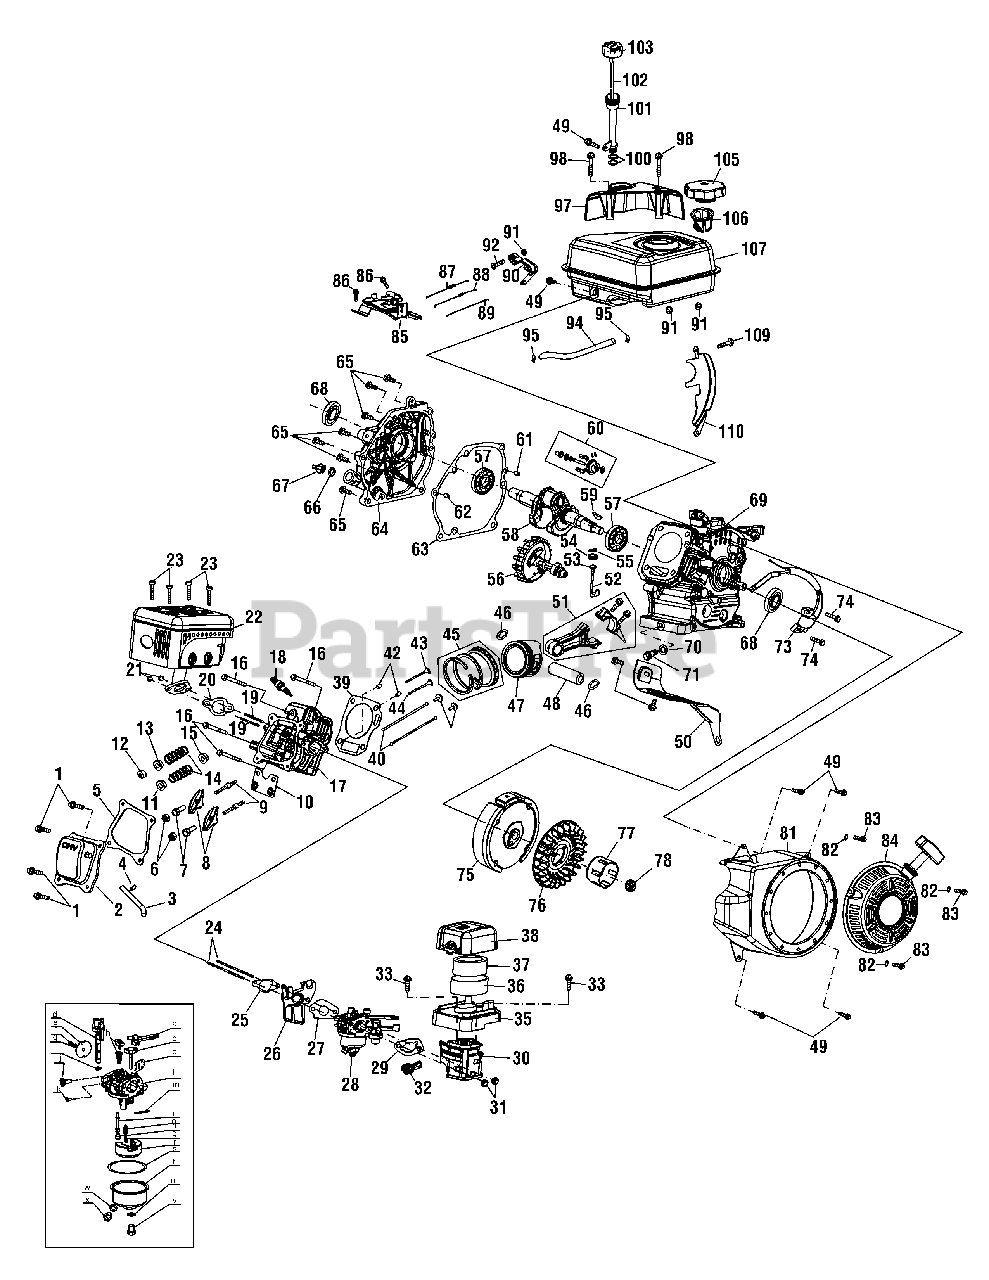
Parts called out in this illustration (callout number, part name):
1	Bolt
2	Valve Cover
3	Breather Hose
4	Breather Hose Clamp
5	Valve Cover Gasket
6	Nut, Pivot Locking
7	Valve Adjusting Nut
8	Rocker Arm
9	Rocker Arm Stud
10	Push Rod Guide
11	Valve Spring Retainer-Intake
12	Exhaust Valve Adjustor
13	Valve Spring Retainer-Exhaust
14	Valve Spring
15	Valve Seal
16	Cylinder Head Bolt
17	Cylinder Head
18	Spark Plug
19	Muffler Stud
20	Exhaust Pipe Gasket
22	Muffler Assembly
23	Bolt
24	Carburetor Stud
25	Carburetor Insulator Gasket
26	Carburetor Insulator
27	Carburetor Gasket
28	Carburetor Assembly
29	Carburetor Gasket Plate
30	Air Cleaner Housing
32	Throttle Control Knob
33	Self-Tapping Bolt
35	Lower Housing
36	Air Cleaner Foam Wrap
37	Air Cleaner Element
38	Upper Housing
39	Cylinder Head Gasket
41	Valve Lifter
42	Dowel Pin
43	Exhaust Valve
44	Intake Valve
45	Piston Ring Set
46	Piston Pin Clip
47	Piston
48	Piston Pin
50	Air Shield
51	Connecting Rod Assembly
52	Governor Arm Shaft
53	Governor Shaft O-Ring
54	Governor Seal
55	Cotter Pin
56	Camshaft Assembly
57	Radial Ball Bearing
58	Crankshaft Assembly
59	Flywheel Key
60	Governor Assembly
61	Dowel Pin, 7 x 14
62	Dowel Pin, 9 x 14
63	Crankcase Cover Gasket
64	Crankcase Cover
65	Bolt
66	O-Ring
67	Oil Filler Plug
68	Oil Seal
69	Crankcase Complete
70	Oil Drain Plug Washer
71	Oil Drain Plug
73	Ignition Coil
75	Flywheel
76	Cooling Fan
77	Starter Cup
78	Nut
81	Blower Housing
82	Washer
84	Recoil Starter Assembly
85	Primer Bracket
87	Governor Spring
88	Throttle Linkage Spring
89	Throttle Linkage
90	Governor Arm
91	Nut
92	Governor Arm Bolt
94	Fuel Hose
95	Hose Clamp
97	Engine/Dipstick Cover
100	O-Ring
101	Dipstick Tube
102	Dipstick Gauge
103	Dipstick Cap
105	Fuel Cap
106	Fuel Filter
107	Fuel Tank
110	Blower Housing Shield
